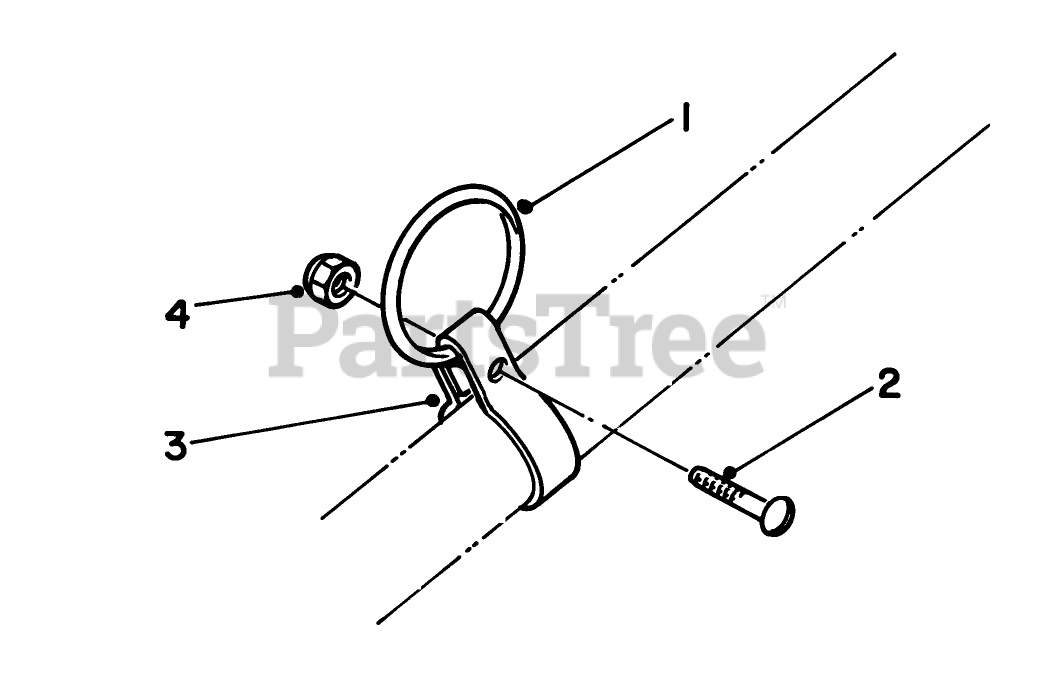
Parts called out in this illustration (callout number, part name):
1	Ring
2	10-24 X 5/8 PAN HD MS
3	Clamp
4	NUT-LOCK, NI
